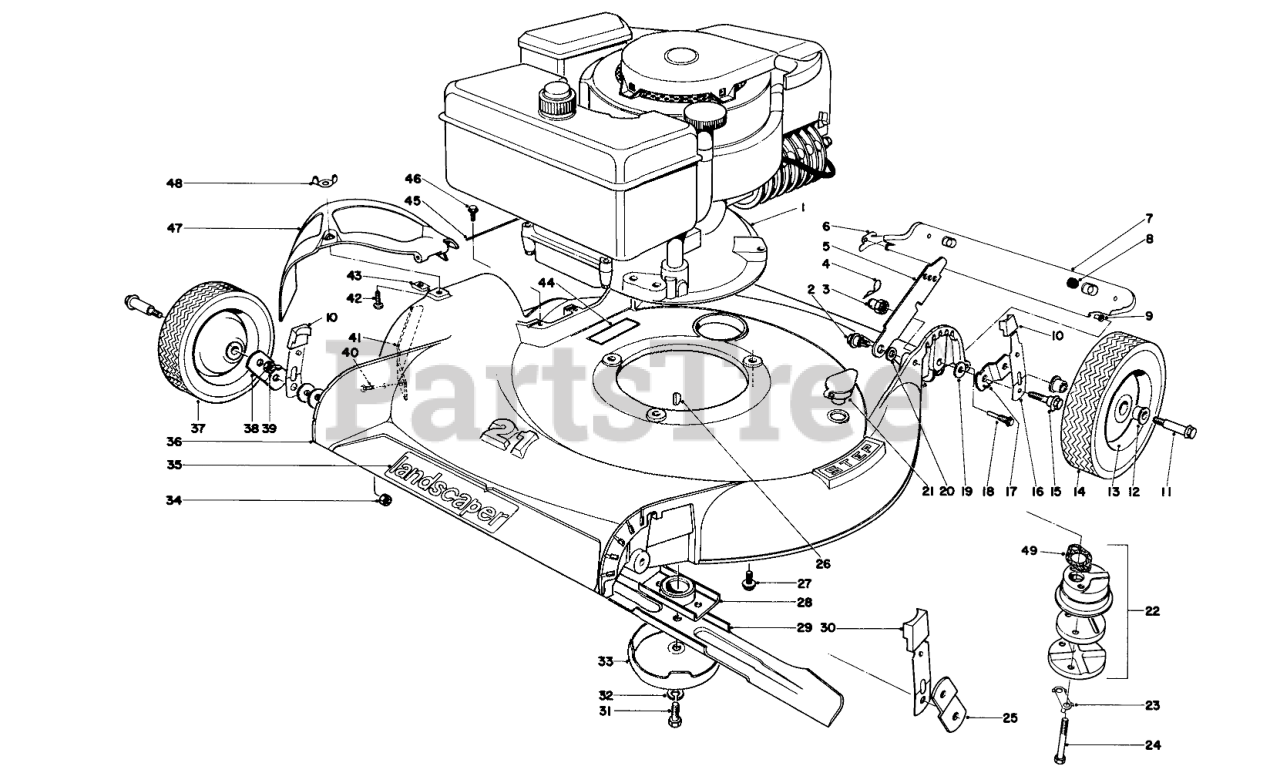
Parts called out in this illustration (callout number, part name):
1	Engine
2	SCREW-SHOULDER
3	HANDLE PIVOT NUT
4	PIN-COTTER, HAIR
5	Latch
6	Restraint R.H.
7	Safety Shield (Incl. Ref. 8 & 9)
8	SKID BUTTON
9	SAFTEY SHIELD BUSHING
10	Arm Knob
12	FLANGE BUSHING
13	Wheel Assembly (Incl. Ref. 12)
14	8 TIRE
15	PIVOT SCREW
16	Spring Arm
17	PIVOT ARM PLATED
18	SAFTEY SHIELD SCREW
19	WASHER-PIVOT
20	SPACER
21	WASHOUT PLUG
22	Muffler Assy. (Incl. Ref. 23 & 24)
23	CLIP - LOCKING
24	SCREW-HH
25	PIVOT ARM C PLTD
26	KEY-WOODRUFF
27	SCREW-HWHTF
28	BLADE RETAINER WA
29	Blade
30	Arm Knob
31	SPECIAL SCREW
32	WASHER-LOCK
33	AntiScalp Cup
34	Nut
35	Decal
36	Housing 21"
38	PIVOT ARM D PLTD
39	Nut
40	SCREW-HWH
41	Bar Safety
43	NUT-SPEED
44	Decal
45	HINGE PIN
46	SCREW
47	Deflector
48	NUT-WING SPECL
49	MUFFLER GASKET
